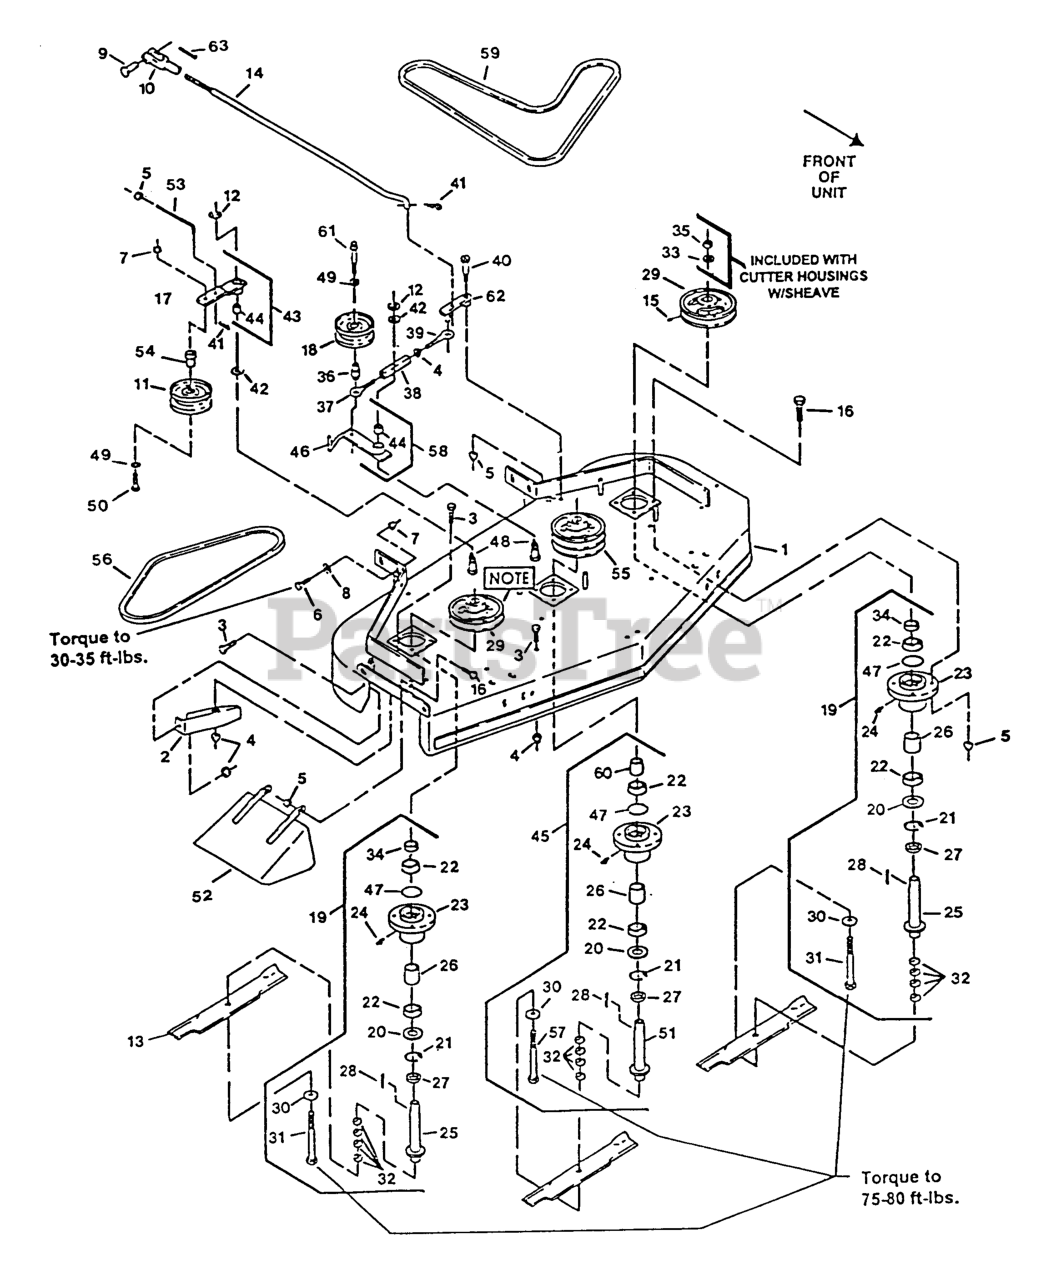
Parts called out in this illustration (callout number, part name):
2	BAFFLE-DOGLEG
9	PIN-CLEVIS
10	YOKE-ADJUSTABLE
11	IDLER,PULLEY
14	ARM-LINKAGE, ASSIST
15	SCREW-SET
17	Arm Weldment, Rh
19	ASM,HOUSING CUTTER
20	SEAL,DUST
21	RING,SNAP WLDS N5000-244
22	BEARING,HD SPINDLE
23	HOUSING,CUTTER
26	SPACER,BRG/BRG
27	SPACER,BEARING &SPINDLE
30	WASHER-SPRING
31	SCREW-CAP, HH
33	WASHER-RETAINER, SHEAVE
36	BUSHING-ENGAGEMENT
37	EYEBOLT-THREAD, LH
38	BODY-TURNBUCKLE
39	EYEBOLT-THREAD, RH
40	BOLT,SHLDR KSKH
41	PIN-COTTER
42	WASHER-SPINDLE
43	ARM WLDMNT W/BUSHING
44	BEARING,POWDERED METAL
52	Chute
53	LINKAGE
54	BUSHING-IDLER
56	BELT,FRONT DECK
57	SCRW,CAP HH 5/8-18X8.5
59	BELT,BLADE DRIVE 36
60	SPACER,BEARING/SHEAVE
